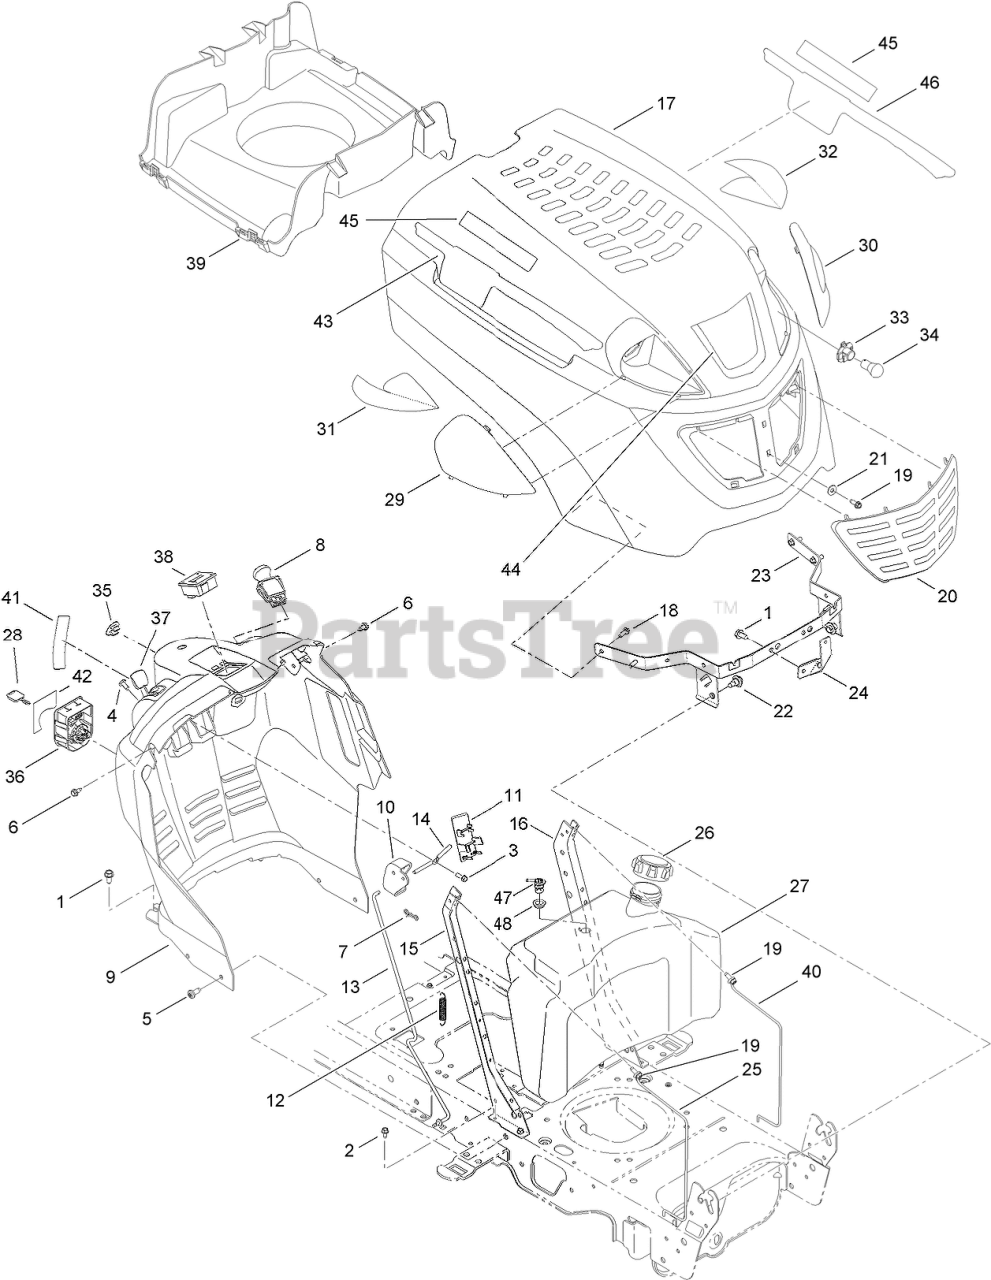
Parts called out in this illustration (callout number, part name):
1	SCREW-TAP
2	SCREW-HWHTF
3	SCREW-TAP
4	SCREW-TAP
5	SCREW-TAP
6	SCREW-HWH
7	PIN-COTTER
8	SWITCH-ELECTRIC, PTO
9	DASH-ELECTRIC, PTO
10	LEVER-DASH
11	COVER-CRUISE
12	SPRING-EXTENSION
13	ROD-LATCH
14	ROD-LEVER, BENT
15	SUPPORT-DASH, PLATE (RH)
16	SUPPORT-DASH, PLATE (LH)
19	SCREW-TAP
21	WASHER-FLAT
22	BOLT-SHOULDER, TAP
23	BRACKET-PIVOT
24	BRACKET-SUPPORT, HOOD
25	ROD-SUPPORT
26	CAP-FUEL
27	TANK-FUEL
28	KEY-IGNITION
29	LENS-RH
30	LENS-LH
31	REFLECTOR-RH
32	REFLECTOR-LH
33	SOCKET-HEADLIGHT
34	LAMP-12V, MINIATURE
35	PLUG-CHOKE
36	MODULE-SWITCH, IGNITION
37	CABLE-THROTTLE
38	METER-HOUR
39	PLENUM-HOOD
40	ROD-SUPPORT, LH TANK
41	DECAL-THROTTLE
42	DECAL-SWITCH, IGNITION
43	DECAL-HOOD, RIGHT SIDE
44	DECAL-HOOD
45	DECAL-SIDE PANEL
46	DECAL-HOOD, LEFT SIDE
47	Valve-Rollover, Grommet
48	Grommet-Rubber
